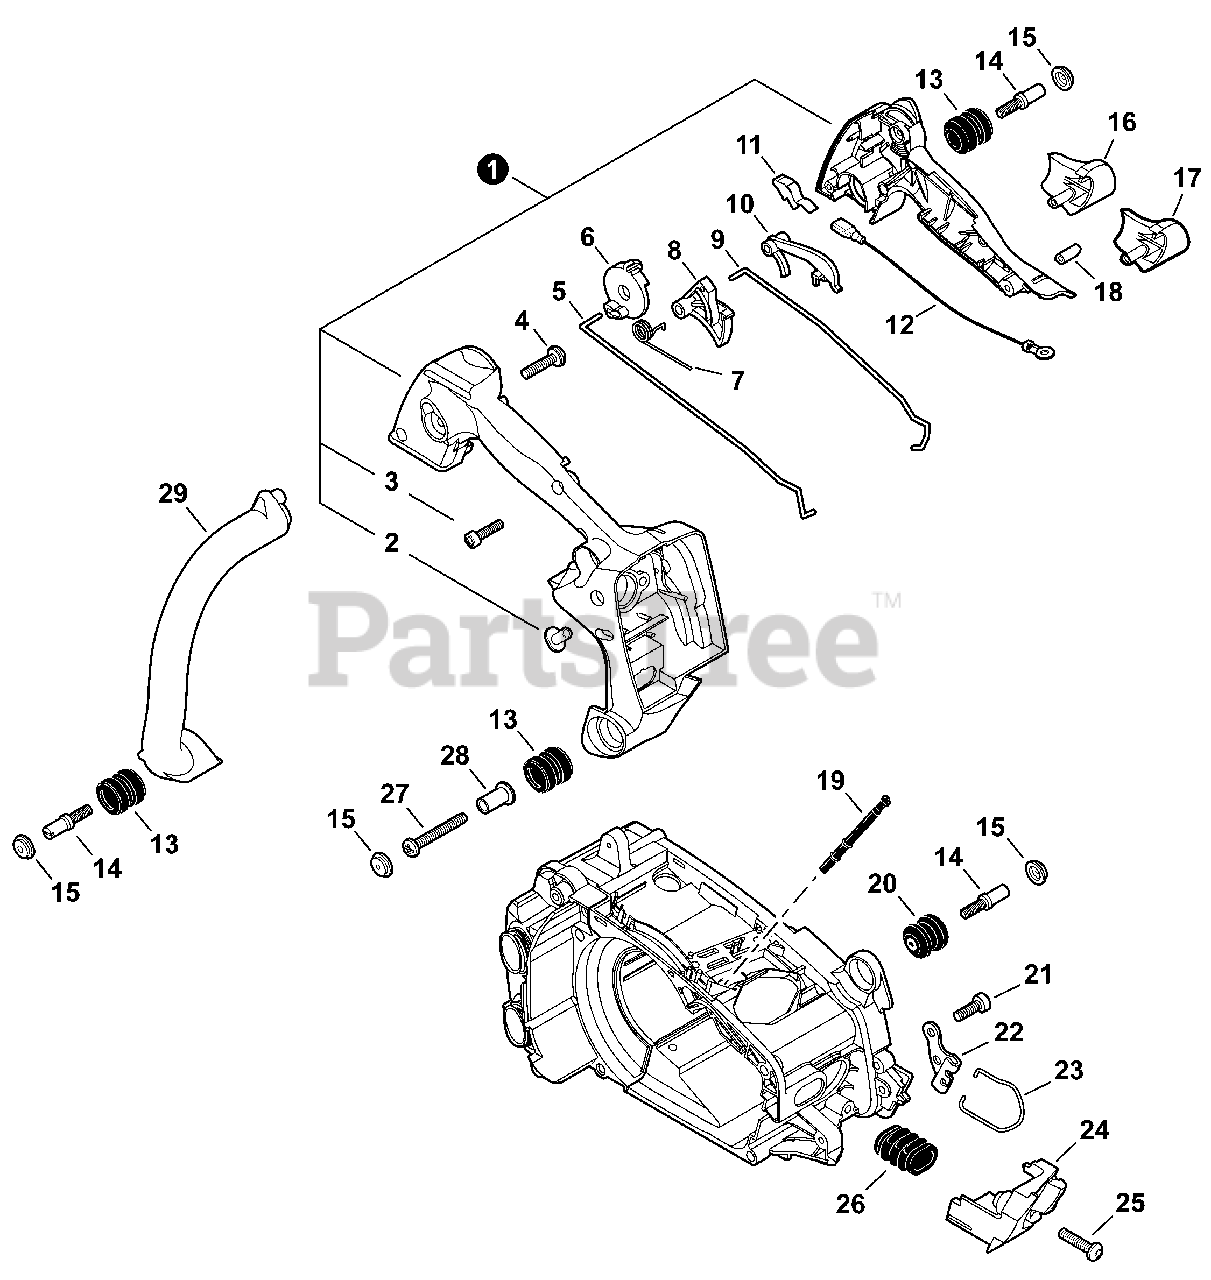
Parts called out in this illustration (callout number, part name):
1	HANDLE SET, REAR
3	BOLT, TORX 4×16
4	BOLT, TORX 5×20
5	ROD, CHOKE
6	LEVER, CONTROL
7	SPRING, TORSION
8	TRIGGER, THROTTLE
9	ROD, THROTTLE
10	LOCKOUT, THROTTLE
11	TERMINAL, GROUND
12	LEAD - GROUND
13	CUSHION 4
14	BOLT 4×12
15	CAP, CUSHION
16	SUPPORT, HANDLE - LARGE
17	SUPPORT, HANDLE - SMALL
19	PIPE, PULSE 3×7×80
20	CUSHION
21	BOLT, TORX 5×12
22	BRACKET, STRAP
23	RING, HARNESS
25	BOLT, TORX 5×20
26	BELLOWS, INTAKE
27	SCREW, TAPPING 4×35
28	COLLAR 4
29	HANDLE, FRONT
